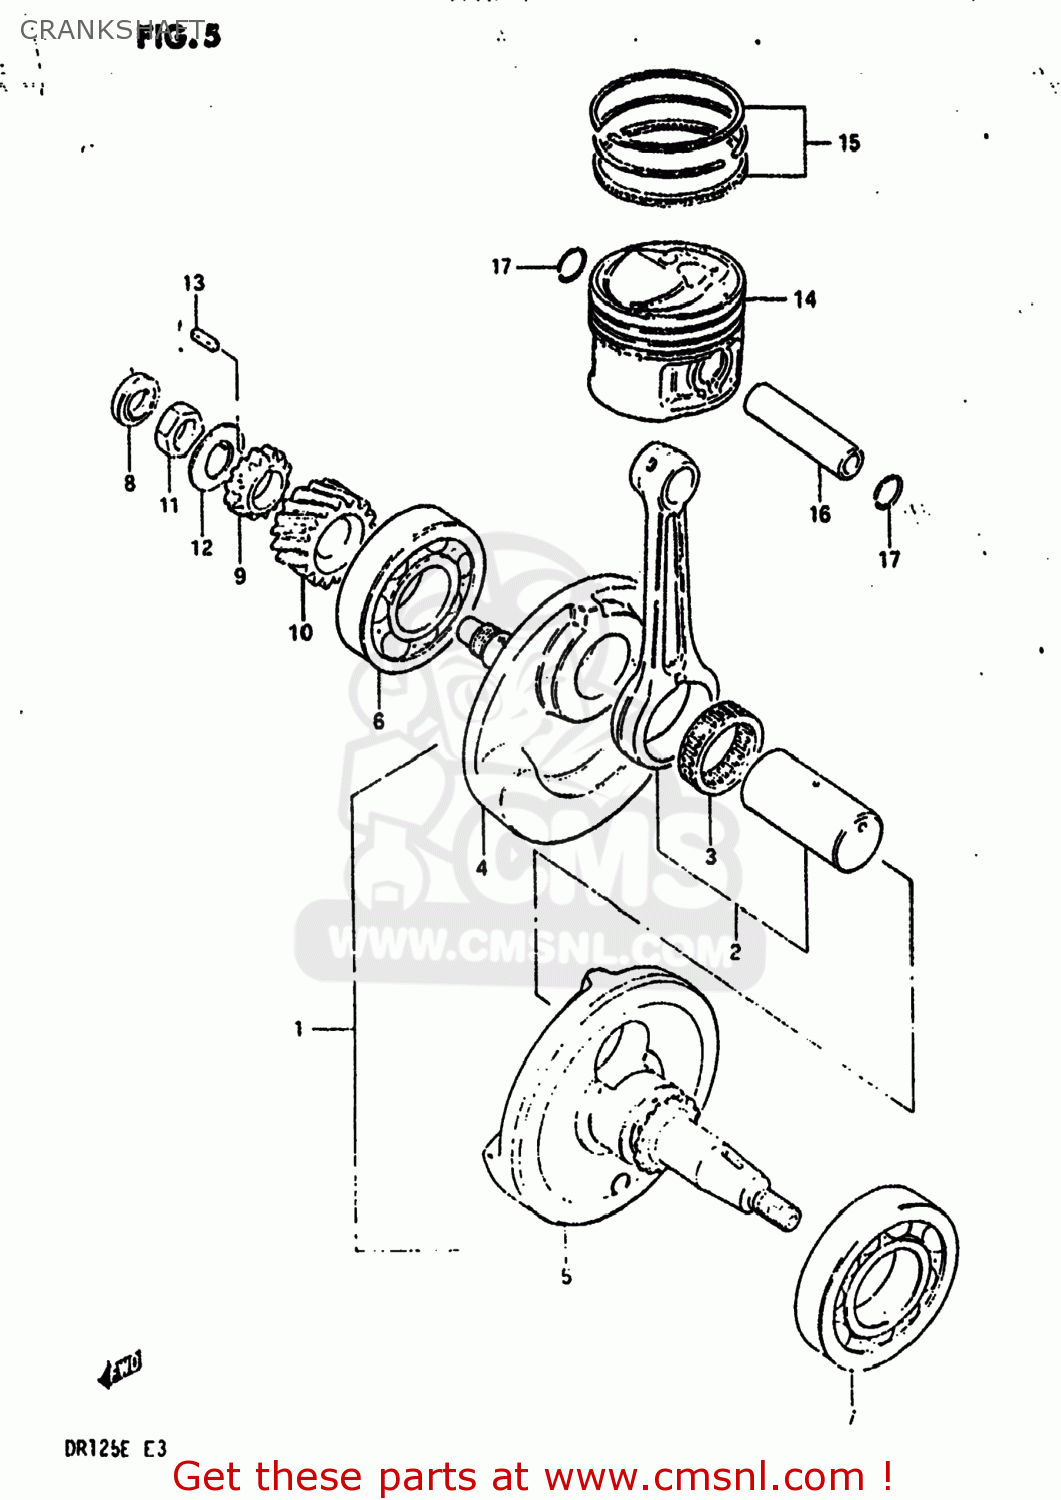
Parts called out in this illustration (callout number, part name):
1	CRANKSHAFT ASSEMBLY
2	CRANKSHAFT ASSEMBLY
3	BEARING
4	CRANKSHAFT
5	CRANKSHAFT,LEFT
6	BEARING,MIDDLE
7	BEARING
8	OIL SEAL
9	GEAR,OIL PUMP DRIVE
10	GEAR,PRIMARY DRIVE
11	NUT
12	WASHER
13	KEY
14	PISTON (STD)
15	RING SET,PISTON
16	PIN,PISTON
17	RING,SNAP 14MM
